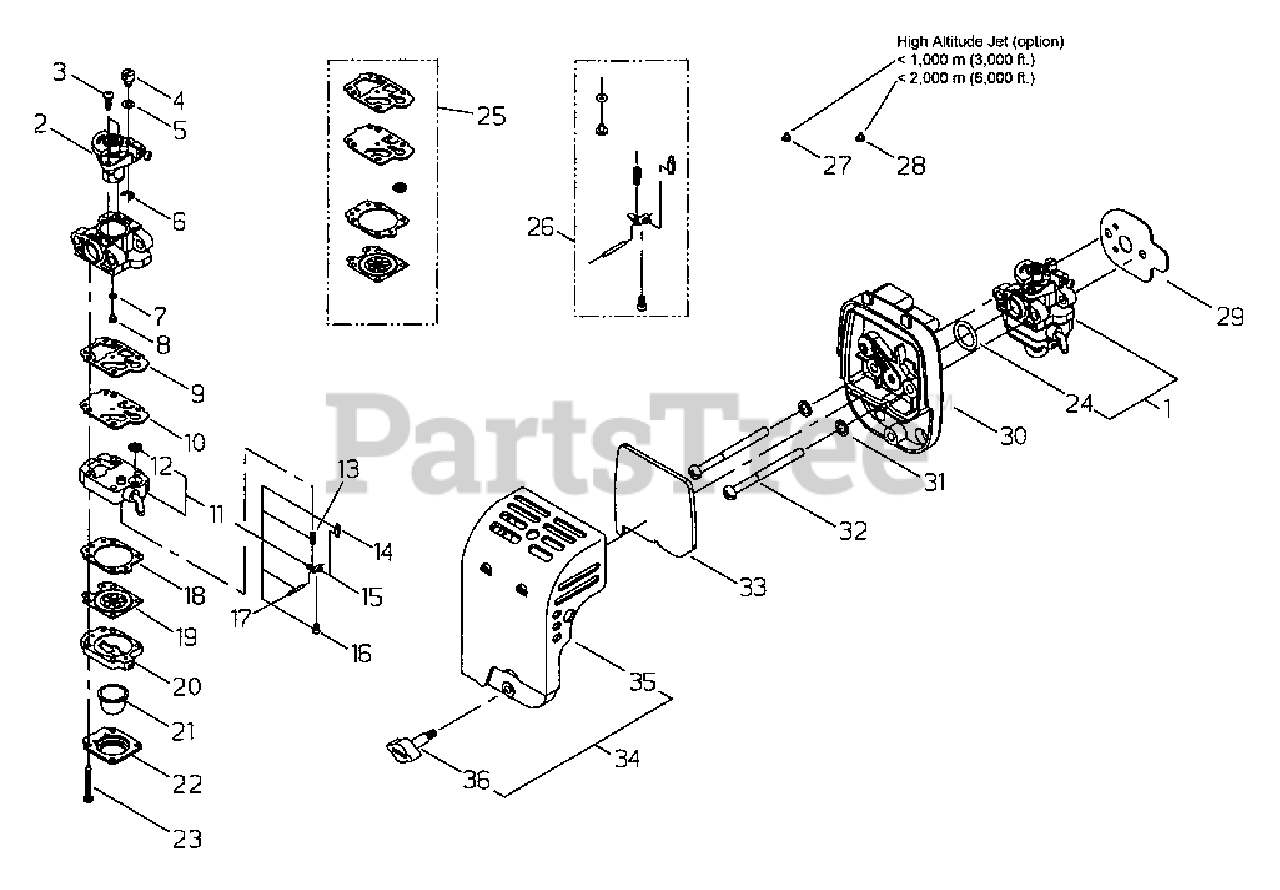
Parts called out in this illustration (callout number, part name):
1	CARBURETOR
2	THROTTLE VALVE ASSY
3	SCREW
4	SWIVEL
5	WASHER
6	RING, RETAINING
7	GASKET, PUMP
8	JET, MAIN
9	GASKET, PUMP
10	DIAPHRAGM, PUMP
11	PUMP BODY ASSY
12	STRAINER
13	SPRING, METERING LEVER
14	VALVE, INLET NEEDLE
15	LEVER, METERING
16	SCREW, METERING LEVER PIN
17	PIN, METERING LEVER
18	GASKET, METERING
19	DIAPHRAGM, METERING
20	BASE, PURGE
21	BULB, PURGE
22	RETAINER, PURGE BULB
23	SCREW, PUMP COVER
24	O-RING - 15
25	DIAPHRAGM/GASKET KIT
26	INLET NEEDLE VALVE KIT
27	JET, MAIN - 1000M
28	JET, MAIN - 2000M
29	GASKET
30	CASE, AIR FILTER
31	WASHER - 5
32	SCREW - 5X60
33	FILTER, AIR
34	AIR FILTER COVER ASSY
35	COVER, AIR FILTER
36	THUMBSCREW
